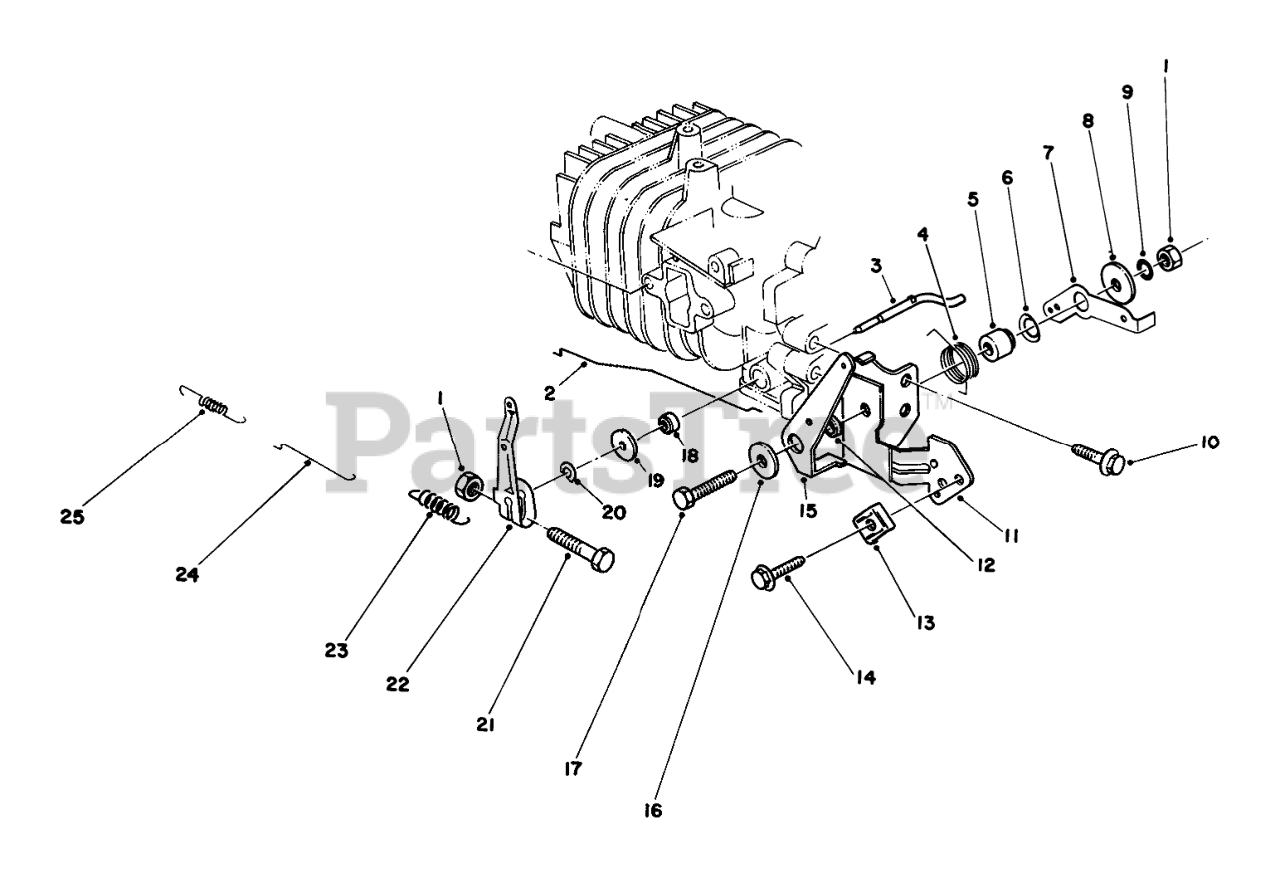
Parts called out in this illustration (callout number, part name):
2	CHOKE ROD
3	Shaft-Govemor
4	SPRING-CHOKE LEVER
5	Gov Lever Spacer
6	Washer-Gov. Spring Lever
7	GOV SPRING LEVER
7	LEVER-SPRING, GOVERNOR
8	WASHER
9	LOCKWASHER
11	BRACKET-THROTTLE, CONTROL
12	SPACER-CHOKE LEVER
13	CLAMP
15	LEVER-CONTROL, CHOKE
16	WASHER
18	SEAL-OIL
19	WASHER
20	E-RING
22	Lever-Throttle Control
22	GOVERNOR ARM
23	GOVERNOR SPRING
23	SPRING-GOVERNOR
24	ROD-CARBURETOR
25	SPRING
